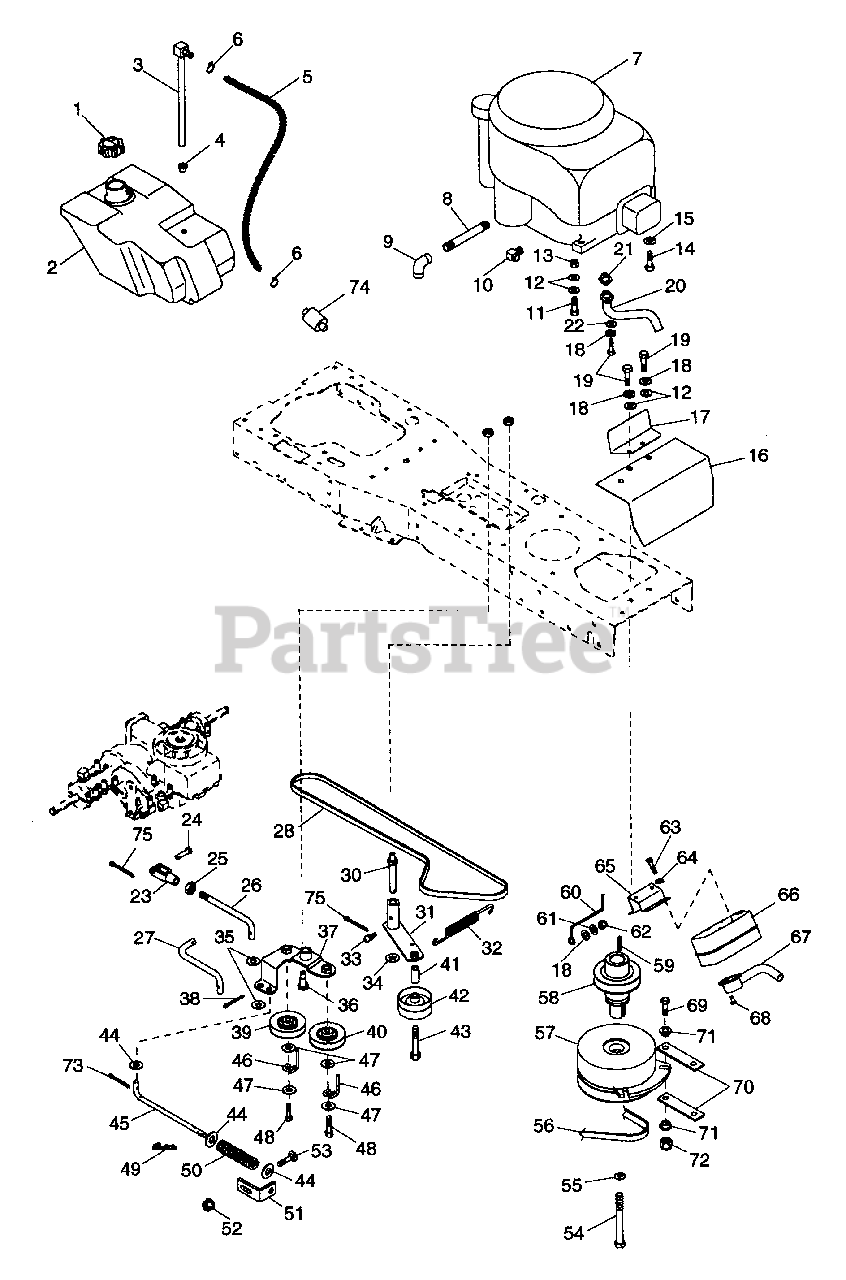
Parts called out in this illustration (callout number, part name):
1	FUEL CAP
2	FUEL TANK
3	TANK FITTING
4	BSHG-FLG .375 X 1.062 X .625 R
5	HOSE- FUEL LINE 34.00"
6	CLAMP-HOSE WIR.490/.510X.092#8
7	ENGINE 12.5HP TEC OHV125-
7	ENGINE 15HP TEC OHV15-
8	NIPPLE
9	ELBOW .375-18 NPTF
10	PIPE FITTING 90 DEG. X 3/8 ELB
11	BLT-HEX .31-18X1.50 PL GR5
12	WSHR-FL-STL .328X.875X.062 PL
13	NUT-LK-TOP .312-18 GR C PL
14	SCR-TAP .375-16X1.25 HWH PL TR
15	WSHR-LK-EXT .375X.050
16	SHIELD
17	HEAT SHIELD
18	WSHR-LK .313X.078 PL MED
19	BLT-HEX .31-18X.75 PL GR5
20	EXHAUST TUBE WELDT- 12.5/13HP
20	EXHAUST TUBE WELDT- 15/16.5HP
21	GASKET- 12.5/13 TEC (#35-414)
21	GASKET:15-16.5HP TEC (#35-438)
22	WSHR-FL-STL .323X.625X.062 PL
23	CLEVIS, .38-24 ADJ.
24	PIN-CLEV .375X.948 YWZC
25	NUT JAM .375-24 PL
26	LINK
27	CLUTCH LINK
28	V-BELT, HA-WRAPPED
28	V-BELT, HA-RAW EDGE
29	NUT-LK-CTR .375-16 GR A PL
30	SHOULDER STUD
31	IDLER PIVOT ARM
32	SG-TENS .080X.470X4.88 WLD 30
33	FTG-LUBE .25-28X.256 YWZC
34	WSHR-FL-STL .520X.827X.062 YZ
35	WSHR-FL-STL.406X.812X.065PL
36	BLT-SHLDR .38-16X1.25
37	IDLER PIVOT ARM
38	PIN-COTR .12X.50 PL
39	IDLER - 2.25X.87
40	IDLER-V 3X.38
41	TUBE
42	IDLER-FLAT 2.75X.38 PAINTED
43	BLT-HEX .38-16X3.00 PL GR2
44	WSHR-FL-STL .328X.555X.06 PL
46	BELT FINGER
47	WSHR-FL-STL .390X.750X.125 PL
48	BLT-HEX .38-16X1.75 PL GR2
49	PIN-HAIR INT .06X.18X.77
50	SG-COMP .080X.550X8.50 WLD38
51	SPRING RETAINER BRKT
52	NUT-FLG. .312-18 PL
53	BLT-RDHDSQNK.31-18X.75GR5SHTPL
54	SCR-CAP .44-20X4.00 GR5 HHPL
55	WSHR-LK .438X.133 HVY
56	V-BELT, 4L-RAW EDGE
57	ELECTRIC CLUTCH/BRAKE(1.8AMP)
58	SHEAVE EXTENSION SHAFT
59	KEY-SQ .25 X 1.25 X .25 SAE
60	BELT FINGER
61	WSHR-FL-STL.312X.734X.065PL
62	NUT-JAM .312-18 PL
63	BLT-HEX .25-20X.50 PL GR2
64	WSHR-LK .250X.077 HVY PL
65	BRACKET WELDT- MUFFLER
66	MUFFLER ASSY
67	TAIL PIPE WELDT
68	SCR-TAP 8-32X.38 SL HWH PL 23
69	BLT-HEX 10-24X1.00 PL GR2
71	SPECIAL WASHER
72	NUT-LK 10-24 NY PL
73	PIN-COTR .06X.50
74	FUEL FILTER
75	PIN-COTR .12X.75 PL
